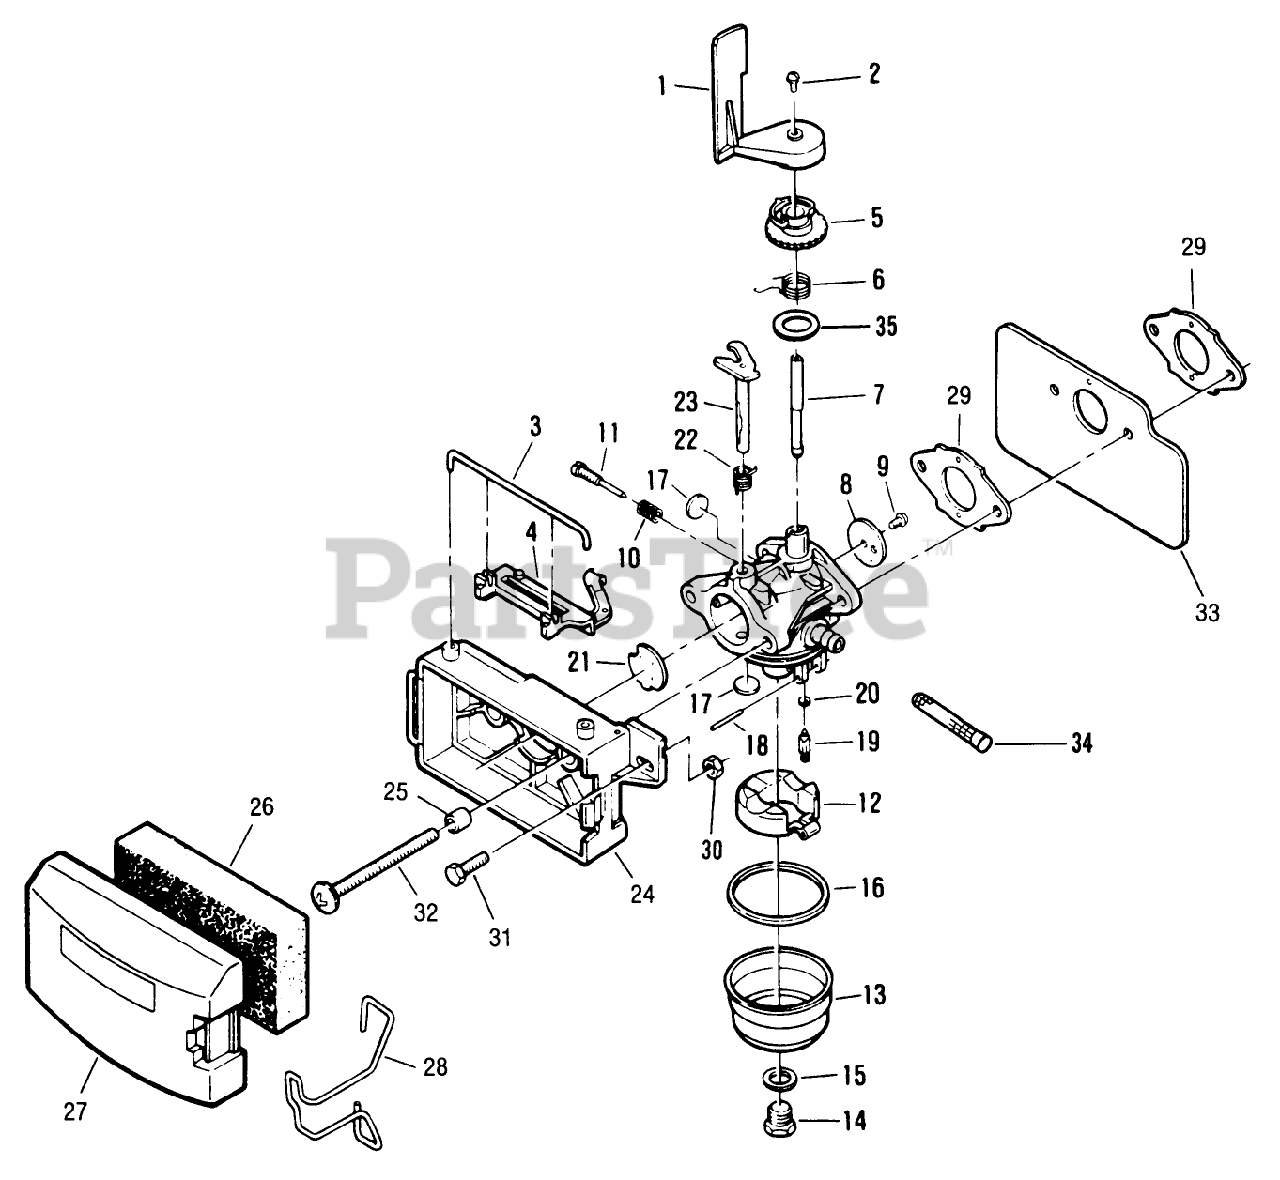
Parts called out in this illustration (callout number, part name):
1	AIR VANE F
2	SCREW F
3	RETAINER
5	COLLAR A/VAVE F
6	THROTTLE SPR E
7	Shaft-Throttle
8	Valve-Throttle
9	Screw-Throttle Valve
10	Spring-Idle Needle
11	Needle-Idle
13	Bowl-Fuel
14	Screw-Bowl Retainer
15	Gasket-Bowl Retainer
16	Gasket-Fuel Bowl
17	Plug-Welch
18	Shaft-Float
19	Valve-Inlet Needle
20	Seat-Valve
21	Valve-Choke
22	Spring-Choke Return
23	Shaft-Choke
25	SPACER
27	Cover-Air Filter
28	RETAINER-COVER, FILTER
29	GASKET CARB S
31	SCREW
32	SCREW
34	SCREEN FUEL PITTS
35	WASHER VF
